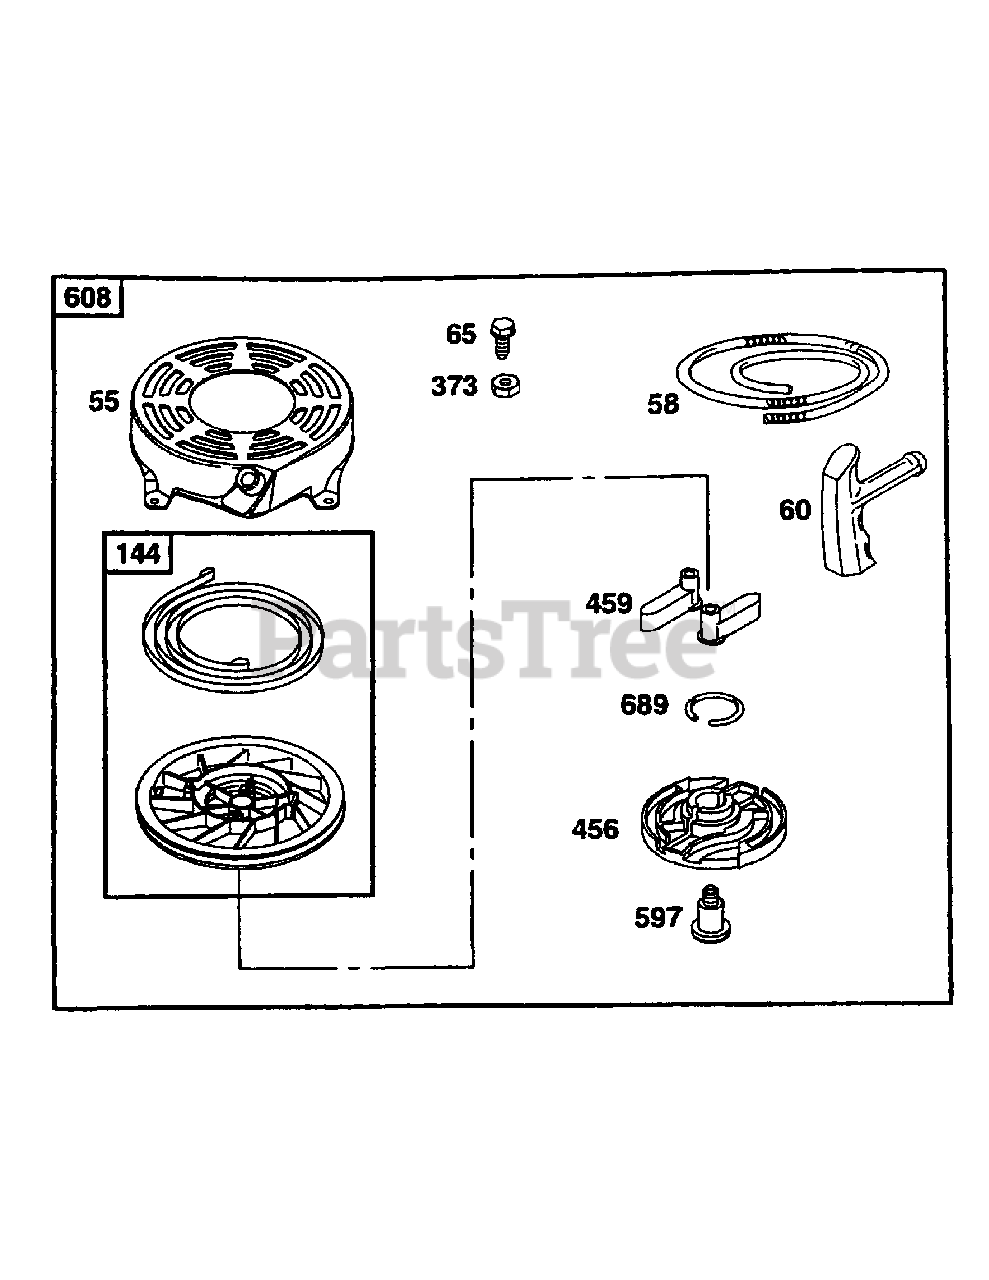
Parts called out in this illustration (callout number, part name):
55	Rewind Starter Housing
58	Starter Rope
60	Starter Rope Grip
65	Hex Screw
144	Starter Pulley
373	Hex Nut
456	Spring Retainer
597	Shoulder Screw
608	Rewind Stater Assembly
689	Friction Spring
